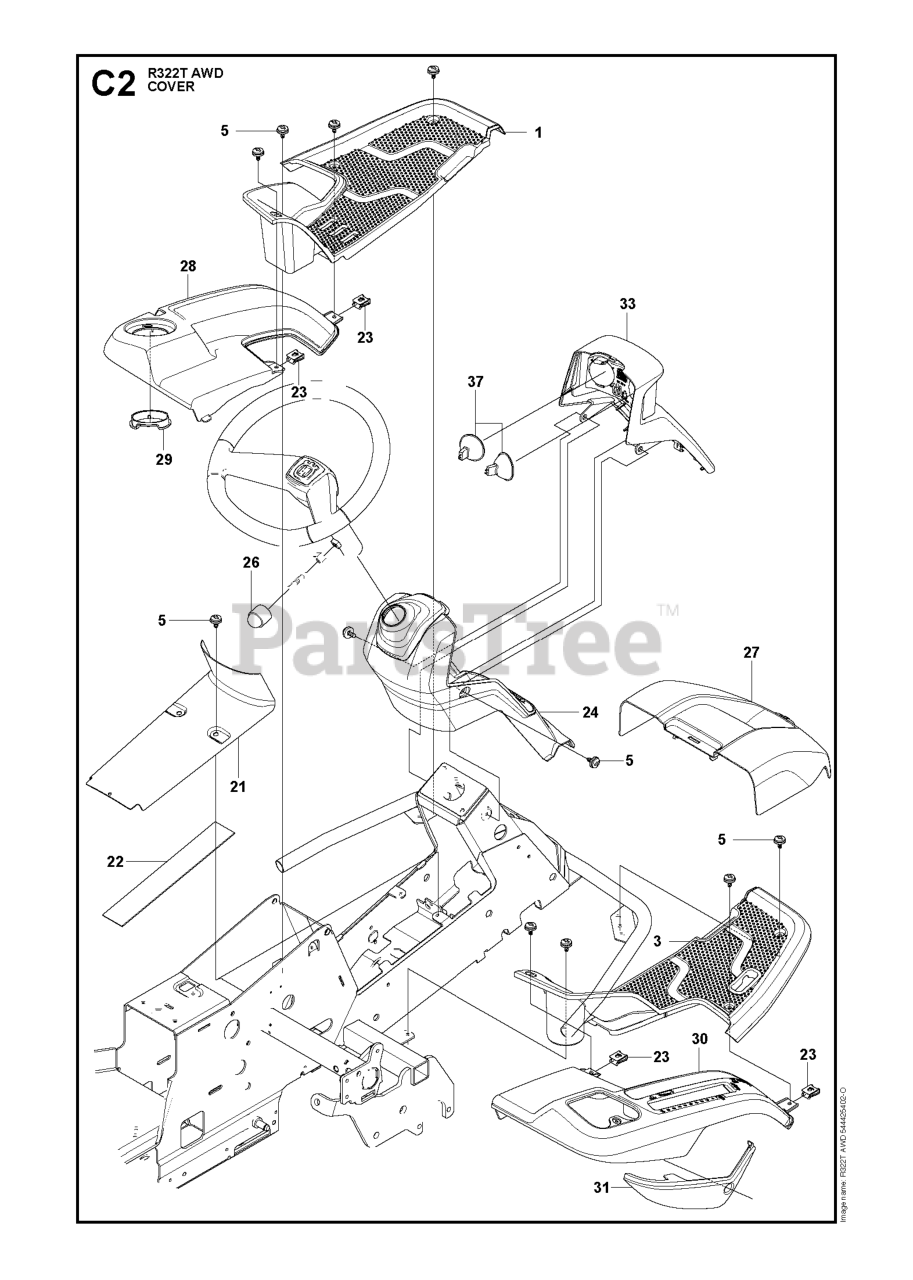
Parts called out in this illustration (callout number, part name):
1	FOOT PLATE
3	FOOT PLATE
26	PROTECTIVE COVER
27	UNIT COVER
29	LOCKING NUT
31	CONTROL COVER
33	COVER
37	LAMP
